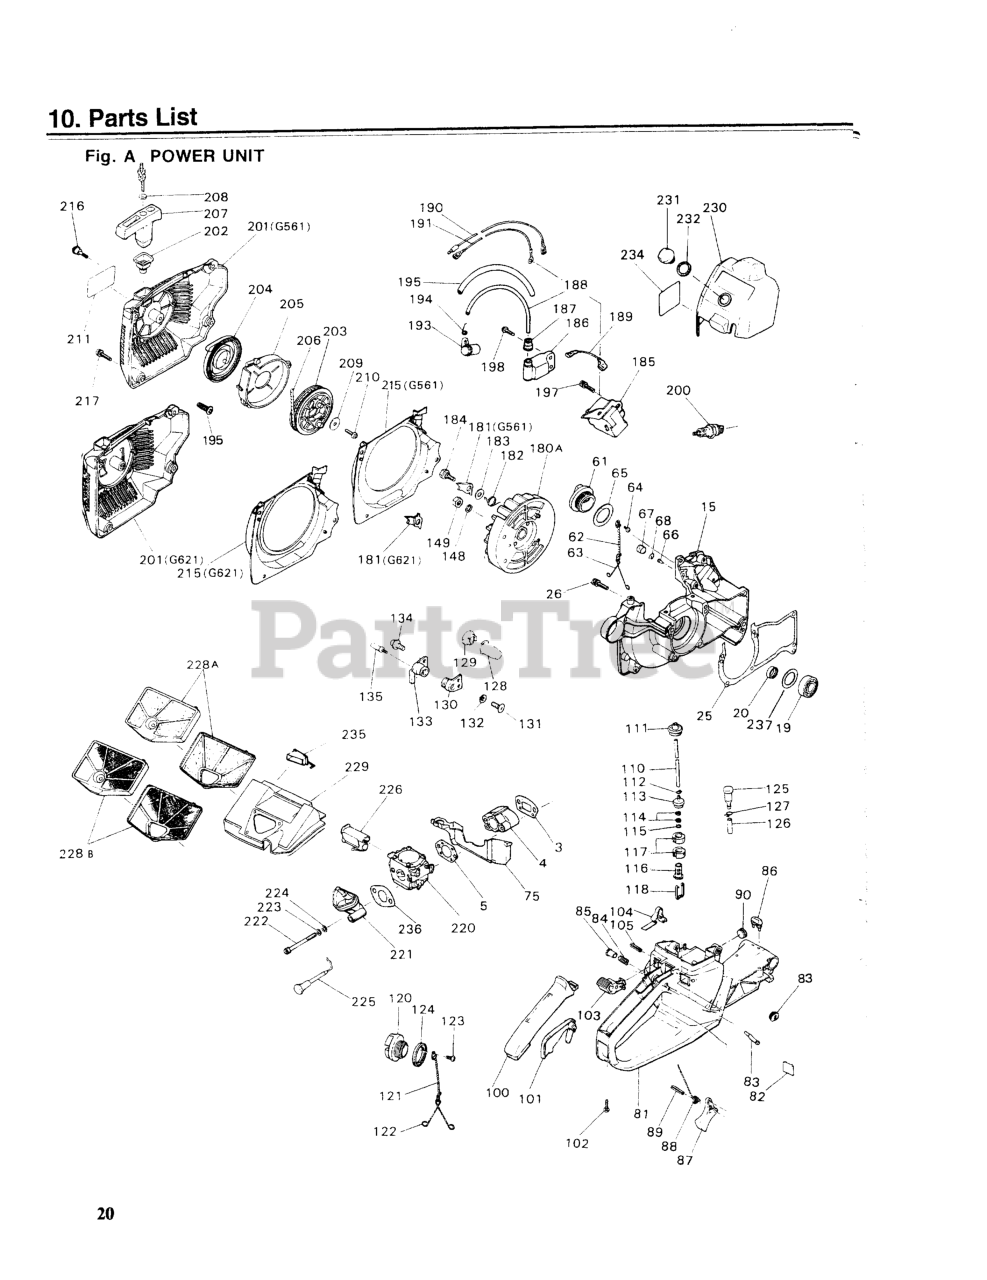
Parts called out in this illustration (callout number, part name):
4	INSULATOR
15	CRANKCASE (USE -21101)
20	SEAL, OIL
25	GASKET (USE -21311)
26	BOLT M5 x 20 (RPLS -12280)
61	CAP ASSEMBLY
62	CAP ASSEMBLY
63	CAP ASSEMBLY
64	SCREW, M4 x 10
65	GASKET
66	VALVE (RPLS -23120)
67	SEAL, BREATHER
68	CLIP
75	SEAL, CYLINDER
81	HANDLE (RPLS -33104)
83	STOPPER
85	KNOB
86	DAMPER (REPLACES 3356-33281)
88	SPRING
90	DAMPER (RPLS -33411)
100	GRIP COVER
101	ARM (USE -33352)
102	SCREW
103	SWITCH LEVER
104	SPRING
105	PIN, SPRING
110	PIPE, SUCTION
111	GROMMET
112	CLIP (REPLACES 2841-31280)
113	FILTER ASSY
114	FILTER ASSY
115	FILTER ASSY
116	FILTER ASSY
117	FILTER ASSY
118	FILTER ASSY
120	TANK CAP ASSY
121	TANK CAP ASSY
122	TANK CAP ASSY
123	SCREW, M4 x 10
124	GASKET
125	BREATHER ASSY (RPLS 2630-31270
127	CLIP (REPLACES 2841-31280)
128	DAMPER (RPLS -35111)
129	CAP (RPLS -35120)
130	DAMPER (RPLS -35150)
131	SCREW, M5 X 14
133	DAMPER (REPLACES -35131)
134	SCREW
148	WASHER, M10 X 25
149	NUT
180A	ROTOR (RPLS -71110)
182	SPRING (REPLACES -71130)
184	BOLT
186	COIL, IGNITION
187	CAP
189	CORD
190	CORD
193	CAP, PLUG
194	SPRING PLUG (RPLS 3310-71320)
197	BOLT
198	SCREW (REPLACES -30414)
201	STARTER (RPLS 2616-75003)
201	RECOIL CASE (RPLS-75103)
202	GUIDE
203	REEL
204	SPRING COMP (RPLS. -75301)
205	SPRING COMP (RPLS. -75301)
206	ROPE
207	KNOB, STARTER
210	SCREW
217	SCREW
220	CARBURETOR (RPLS -81001)
221	MANIFOLD (RPLS -82112)
223	WASHER, SPRING M4 x 1.3
224	WASHER, M5 X .8
225	ROD, CHOKE
226	GUIDE ADJUST
228A	CLEANER, AIR C (RPLS -83103)
229	SILENCER, USE 3369-83200
230	COVER (RPLS -83300)
232	GASKET, KNOB
235	CAP, SILENCER
236	GASKET
237	RING
NI	R HANDLE ASSY (RPLS -33002)
NI	PIPE ASSEMBLY
NI	BREATHER ASSEMBLY
NI	ROTOR COMP.
